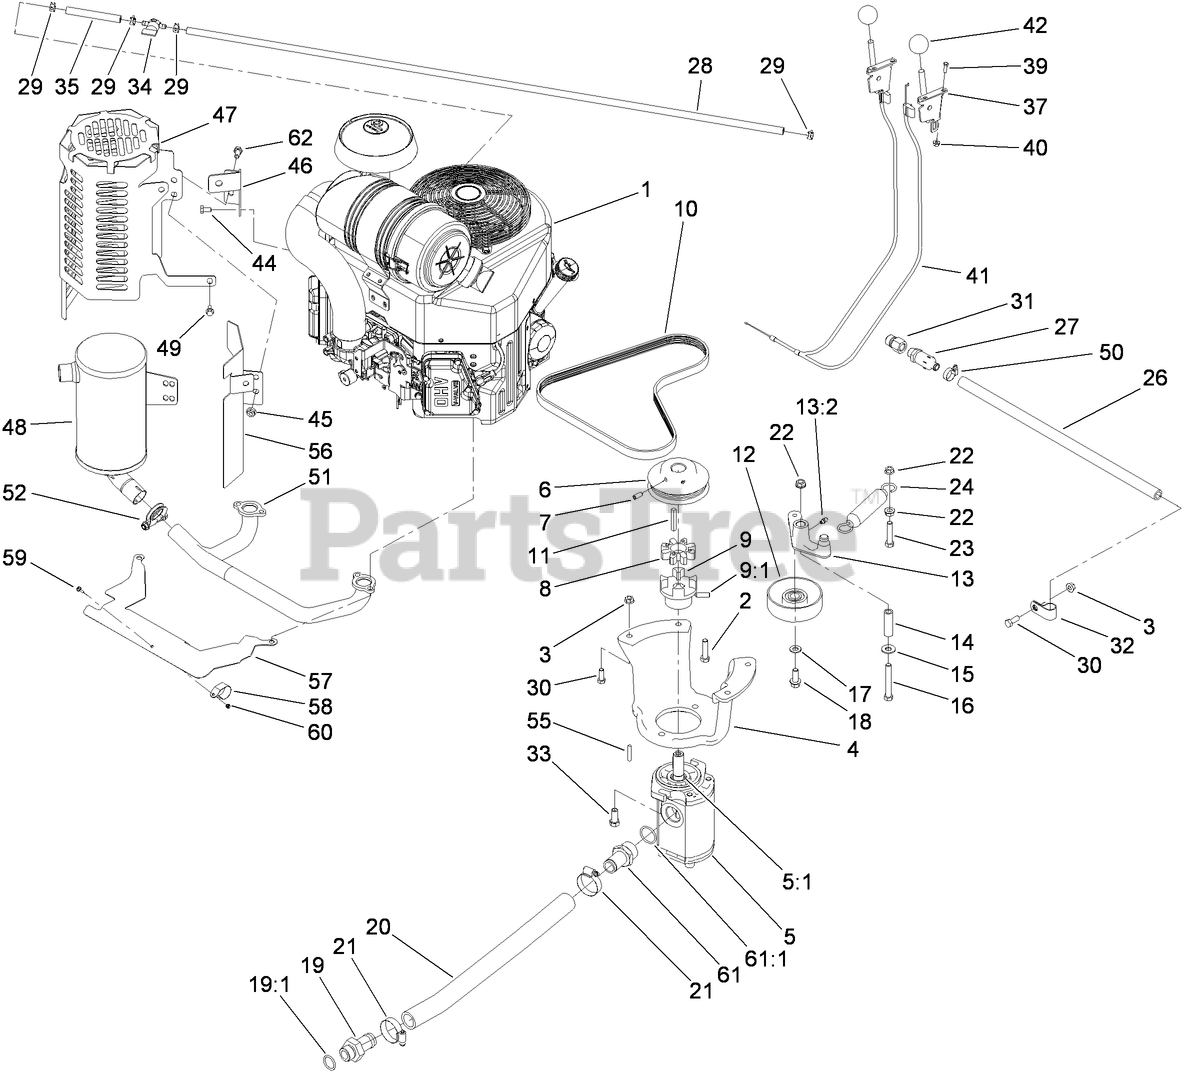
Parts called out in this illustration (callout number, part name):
1	ENGINE-KAWASAKI, FX730V
2	SCREW-HH
3	NUT-HF
4	MOUNT-PUMP
5	GEAR PUMP ASM
5:1	SEAL-WIPER
6	PULLEY-ENGINE
7	SCREW-SET, HSH
8	COUPLER-SPIDER
9	COUPLER-FLEX
9:1	SCREW-SET
10	BELT-V
11	KEY-SQUARE
12	PULLEY-IDLER
13	IDLER ARM ASM
13:2	FITTING-GREASE
14	BUSHING-IDLER
15	WASHER-FLAT
16	SCREW-HH
17	WASHER-FLAT
18	SCREW-HHF
19	FITTING
19:1	O-RING
20	HOSE-SUCTION
22	NUT-HHF, WHIZ
23	SCREW-HH
24	Spring-Extension
26	HOSE-VENT
27	VALVE-DRAIN, OIL
28	HOSE-FUEL
29	CLAMP-HOSE
30	SCREW-HH
31	Adapter
32	CLAMP-R
33	SCREW-HH
34	VALVE-FUEL
35	HOSE-FUEL
37	LEVER-CONTROL
40	NUT-LOCK, FLANGE
41	CABLE-CONTROL
44	SCREW-HH
45	NUT-HF
46	BRACKET-MOUNT, MUFFLER
47	SHIELD-MUFFLER
48	MUFFLER
49	SCREW-HHF
50	CLAMP-HOSE
51	MANIFOLD
52	CLAMP-MUFFLER
55	KEY-SQUARE
56	BRACKET-SHIELD, HEAT
57	PLATE-SHIELD, HEAT
59	SCREW-PAN
60	NUT-HEX
61	FITTING-STR
61:1	O-RING
62	SCREW-HH
